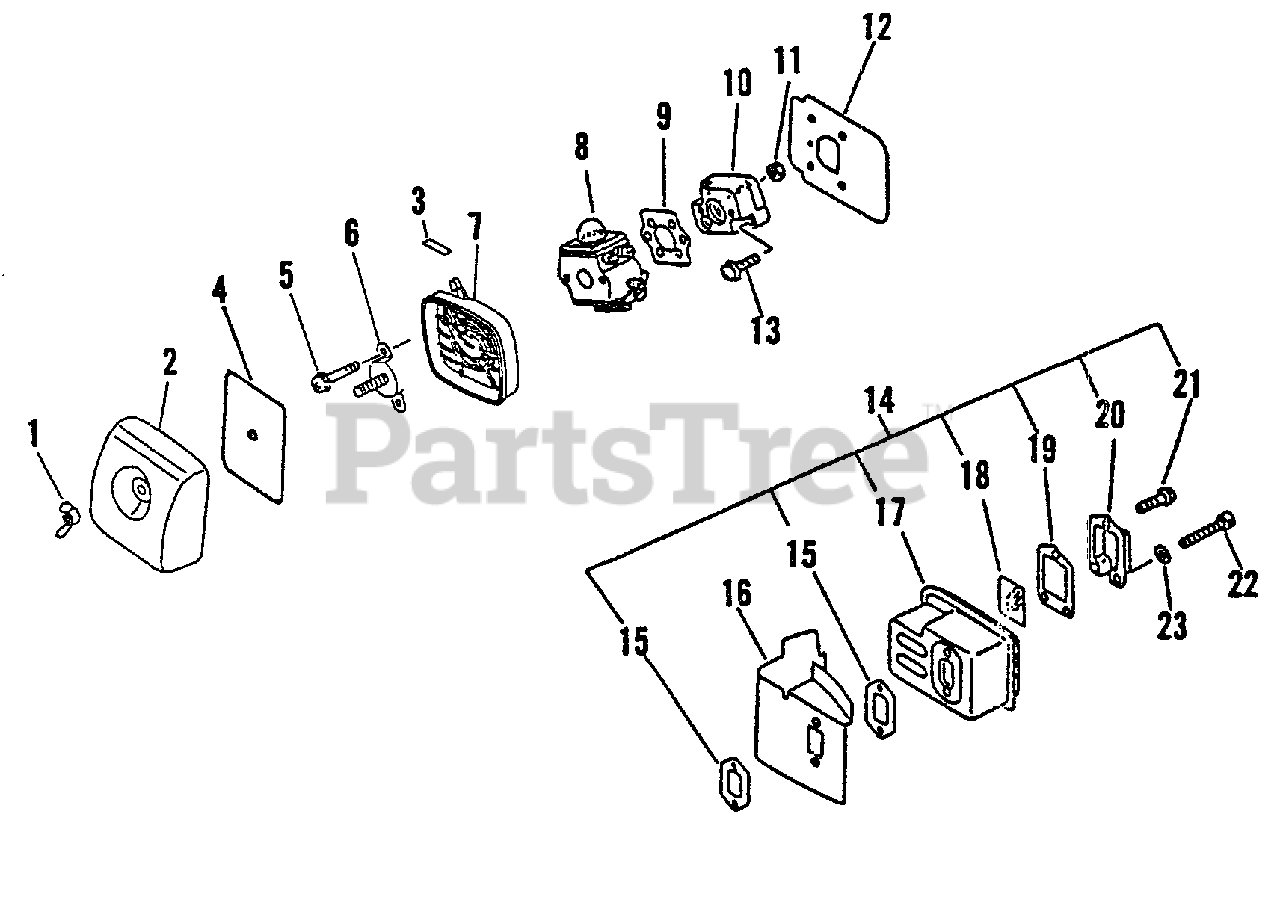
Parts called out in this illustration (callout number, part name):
1	WINGNUT - 6
2	COVER, AIR FILTER - BLACK
3	LABEL, CHOKE
4	FILTER, AIR
5	SCREW 5×65
6	PLATE, PREVENT
7	CASE ASSY, AIR FILTER
8	CARBURETOR - C1U-K27B
9	GASKET, INTAKE
10	INSULATOR, INTAKE
11	NUT M5
12	HEAT SHIELD, INTAKE
13	SCREW 5×20
14	MUFFLER ASSY
15	GASKET, EXHAUST
16	COVER, MUFFLER
18	SCREEN, SPARK ARRESTER
19	GASKET, EXHAUST
20	GUIDE, EXHAUST - INNER
21	SCREW 4×10
22	BOLT M5×50
23	WASHER, FLAT 5.5×10×0.8
